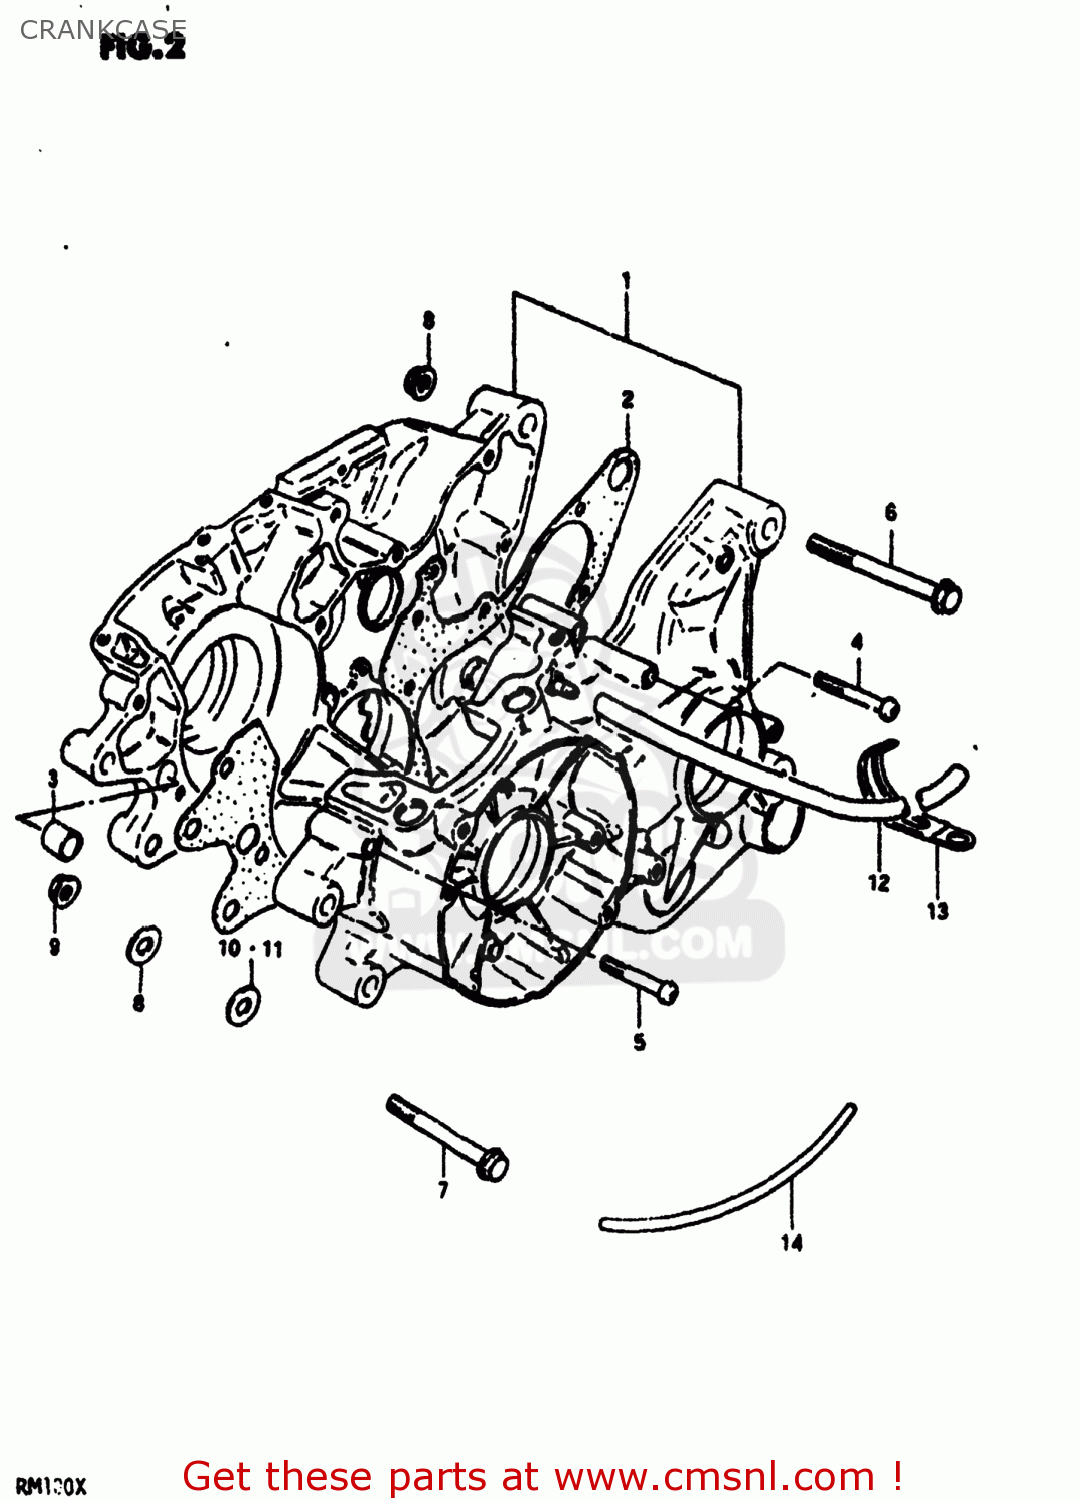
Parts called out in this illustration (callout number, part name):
1	CRANKCASE SET
2	GASKET,CRANKCASE (MCA)
3	PIN
4	SCREW
5	SCREW (6X45)
6	BOLT
7	BOLT(8X67)
8	WASHER
9	NUT
10	WASHER
11	WASHER
12	HOSE
13	CLAMP
14	HOSE
